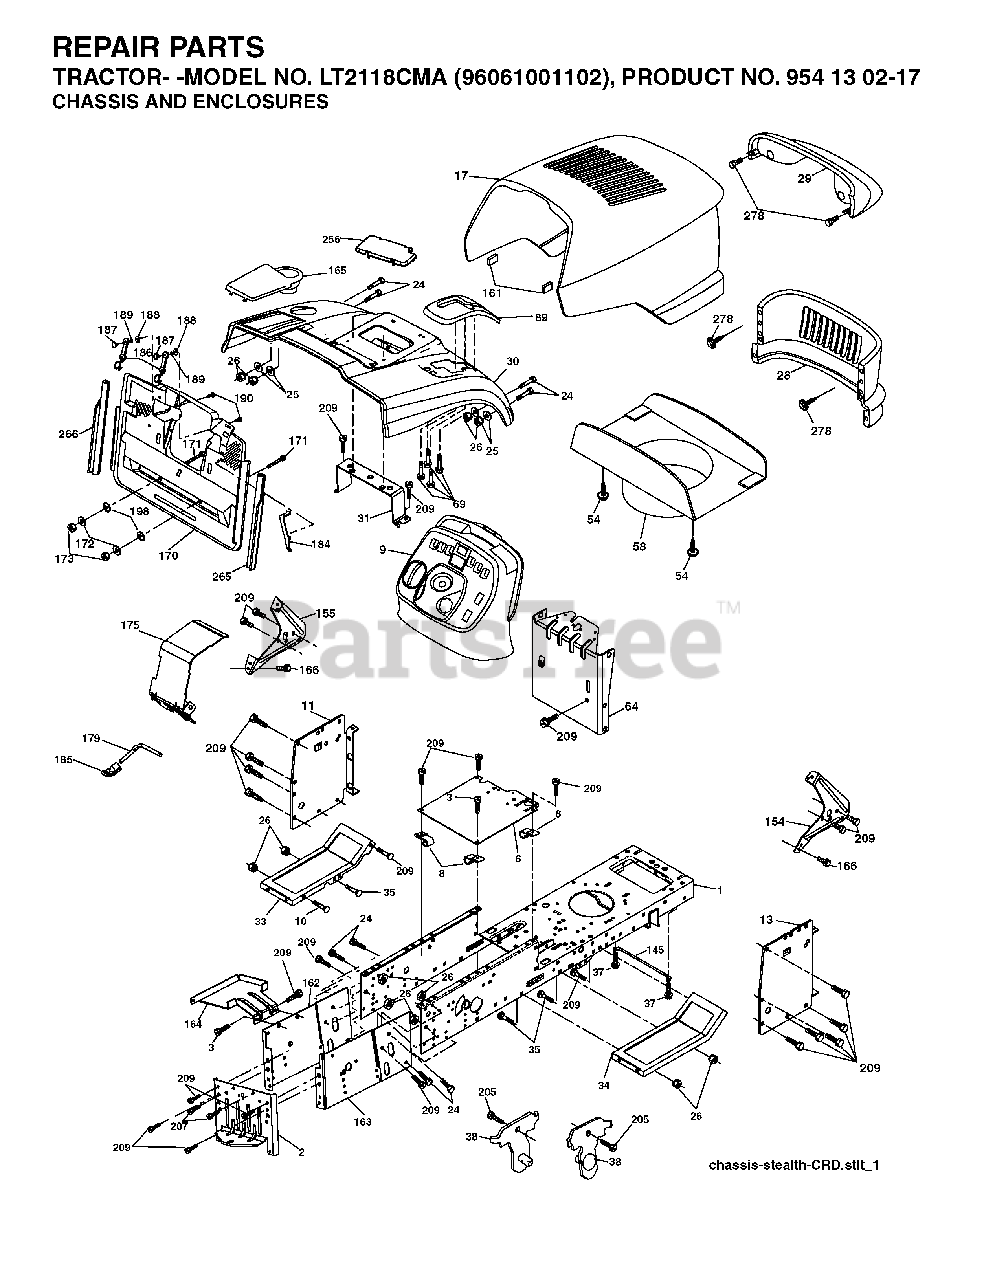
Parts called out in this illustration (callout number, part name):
1	CHASSIS
3	SCREW 3/8-16X3/4
8	CLIP,INSULATOR
10	BOLT D
13	PANEL DASH RH
25	WASHER
26	NUT
31	BRACKET SUPPORT FENDER
58	DUCT HOOD
69	SCREW.HI-LO.CONSOLE
145	ROD PIVOT CHASSIS/HOOD
161	EXTRUSION BUMPER
164	SUPPORT
166	SCREW
171	BOLT
172	WASHER
186	LATCH ASSY
187	WELDNUT
189	LOCKWASHER
207	SCREW, 5/16-18 X 1/2
209	SCREW, 3/8-16X3/4
278	SCREW
